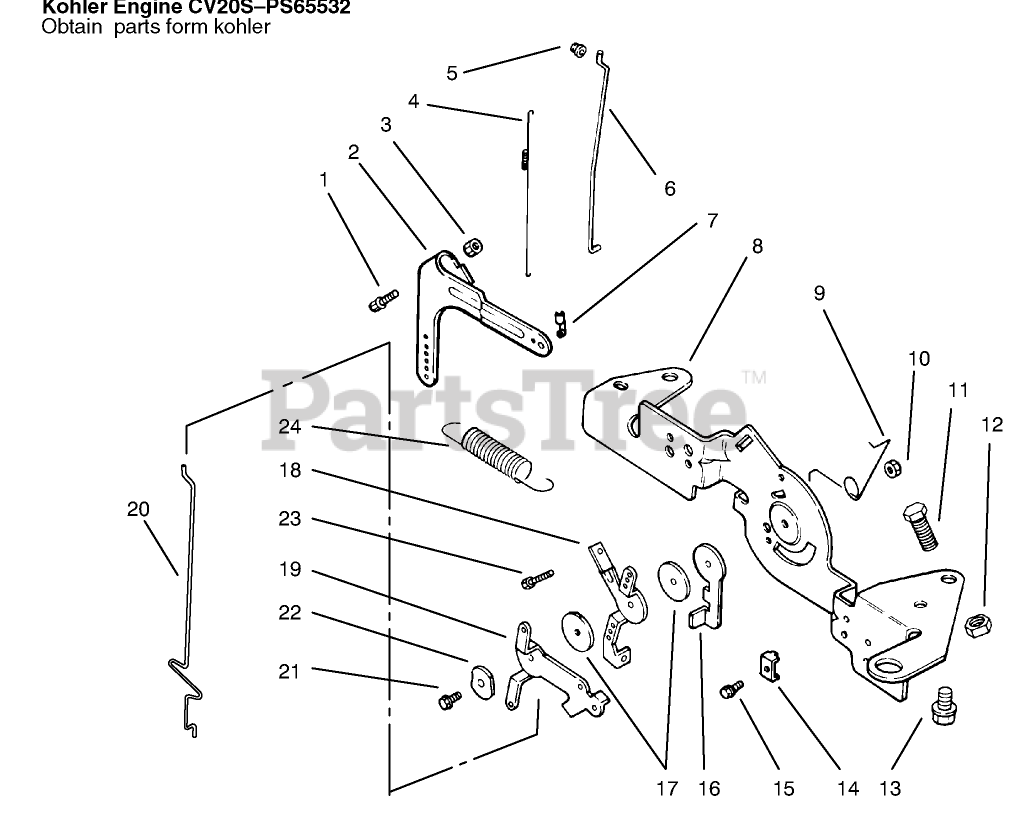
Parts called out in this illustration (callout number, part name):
2	Lever-Governor (Only On: 72103)
4	Spring-Linkage
5	Bushing
6	Linkage-Throttle (Only On: 72103)
7	Bushing-Linkage
8	Bracket-Control
9	Spring-Choke Return
10	Nut M5x0.8 (Only On: 72103)
16	Lever-Throttle Actuator
18	Lever-Throttle Control
19	Lever-Choke
20	Linkage-Choke (Only On: 72103, 72083)
22	Washer-Wave
24	Spring-Governor
